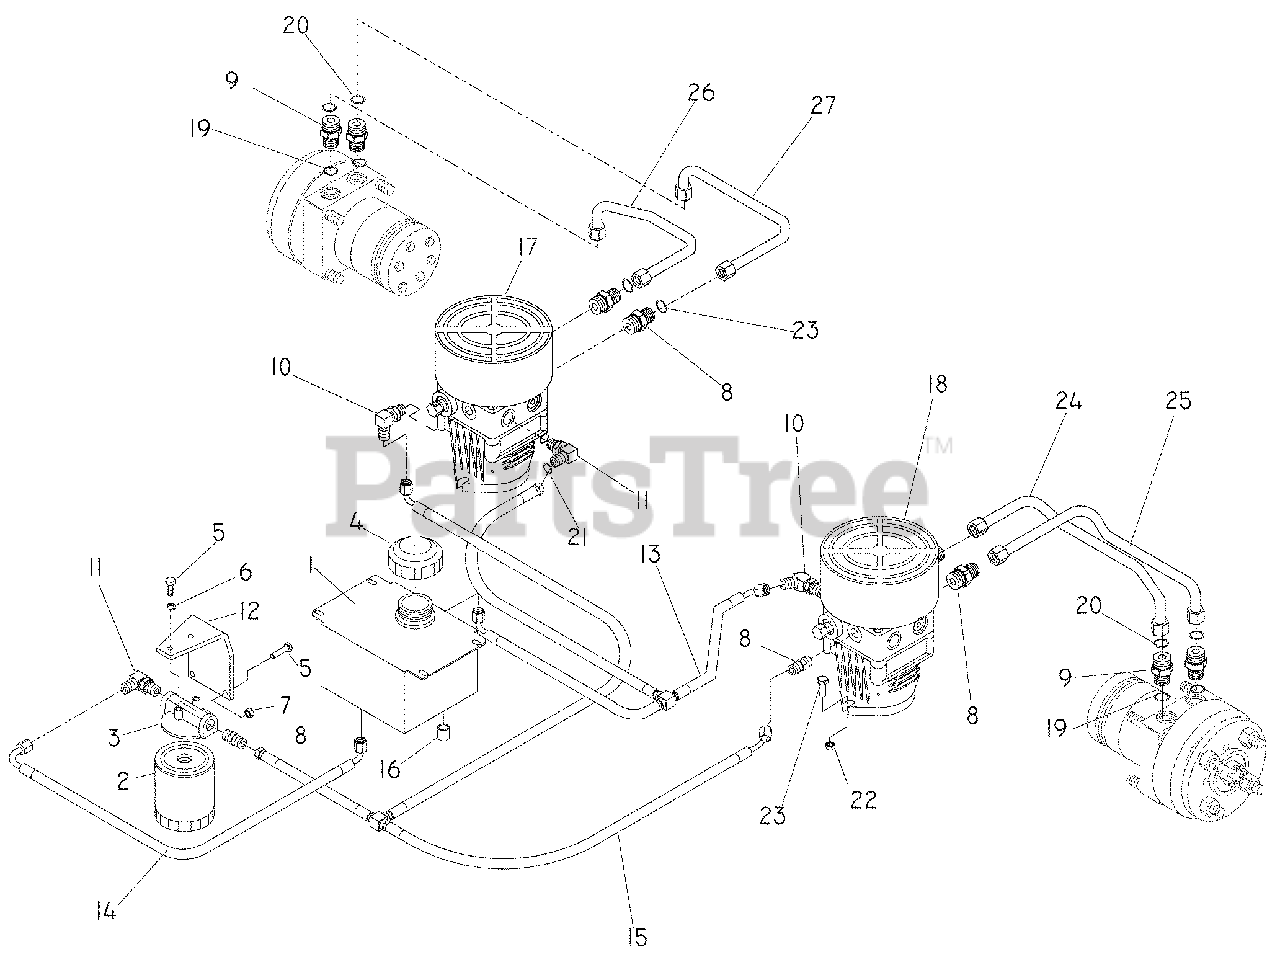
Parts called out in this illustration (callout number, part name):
3	FILTER HEAD
4	HYDRAULIC CAP
5	HCS, ¼ - 20 x ¾
6	LOCKWASHER, ¼
7	NUT ¼-20 HEX NYLOC ZD
8	HYDRAULIC FITTING
9	STRAIGHT FITTING
12	BRACKET, FILTER
13	‘T’ ASSEMBLY, RETURN
14	HOSE
15	‘T’ ASSEMBLY, SUPPLY
17	PUMP W/FANS, 10CC, RT
18	PUMP W/FANS, 10CC, LT
19	‘O’ RING
20	‘O’ RING
21	‘O’ RING
22	NUT 3/8-16, CENTERLOCK
23	HCS 3/8-16 x 1 WHIZLK
24	HYDRAULIC LINE
25	HYDRAULIC LINE
26	HYDRAULIC LINE
27	HYDRAULIC LINE
